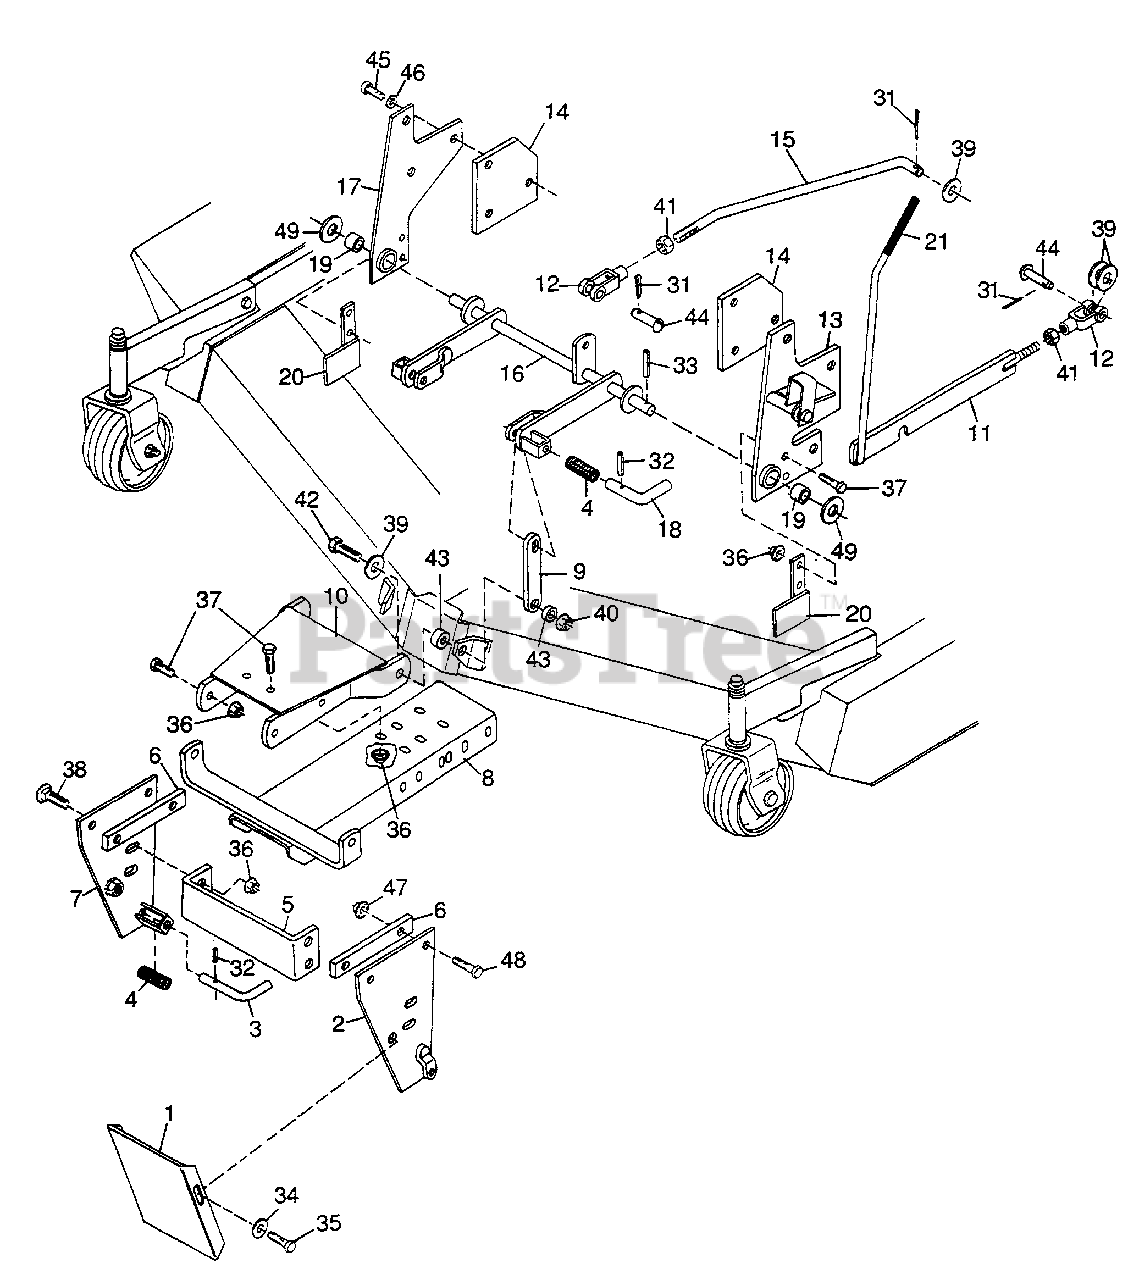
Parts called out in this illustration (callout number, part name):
1	Front mounting plate cover
2	Left front mounting bracket
3	Pin, Bent .5 dia. x 1.96
4	Compression spring, .06 x .66 x 2.5
5	Mounting plate brace bar, 11.69
6	Link, .62 x 1.75 x 7.31
7	Right front mounting bracket
8	Front adjustable channel
9	Link, .38 x 1.5 x 7.88
10	Rear adjustable channel
11	Lock-up bar
12	Adjustable clevis yoke, .50-13 x 3.0
13	Left front lift stop
14	Loader plate, .38 x 5.5 x 6.5
15	Bent pin, .5 x 19.3 x 1/2-13 NC
16	Front rockshaft assembly
17	Right front lift stop
18	Bent pin, .5 x 1.62
19	1.015 x 1.25 x 1 Oilite bushing
20	Lift stop extension
21	Handle grip
31	3/16 x 1 Cotter pin
32	3/16 x 1-1/8 spring pin
33	1/4 x 2 Spirol pin
34	5/16 Standard flat washer
35	5/16 NC x 3/4 Hex head cap screw GR5
36	3/8 NC Flanged hex locknut
37	3/8 NC x 1 Hex head cap screw GR5
38	3/8 NC x 1-1/4 Carriage bolt
39	1/2 Standard flat washer
40	1/2 NC Flanged hex locknut
41	1/2 NC Hex jam nut
42	1/2 NC x 2 Hex hex head cap screw GR5
43	1/2 x 3/4 x 1/2 Sleeve
44	1/2 x 1-3/4 Clevis pin
45	14mm x 2.0 P x 40mm Hex head cap screw
46	9/16 Standard lockwasher
47	5/8 NC Hex locknut
48	5/8 NC x 2 Hex head cap screw GR5
49	1" SAE Flat washer
